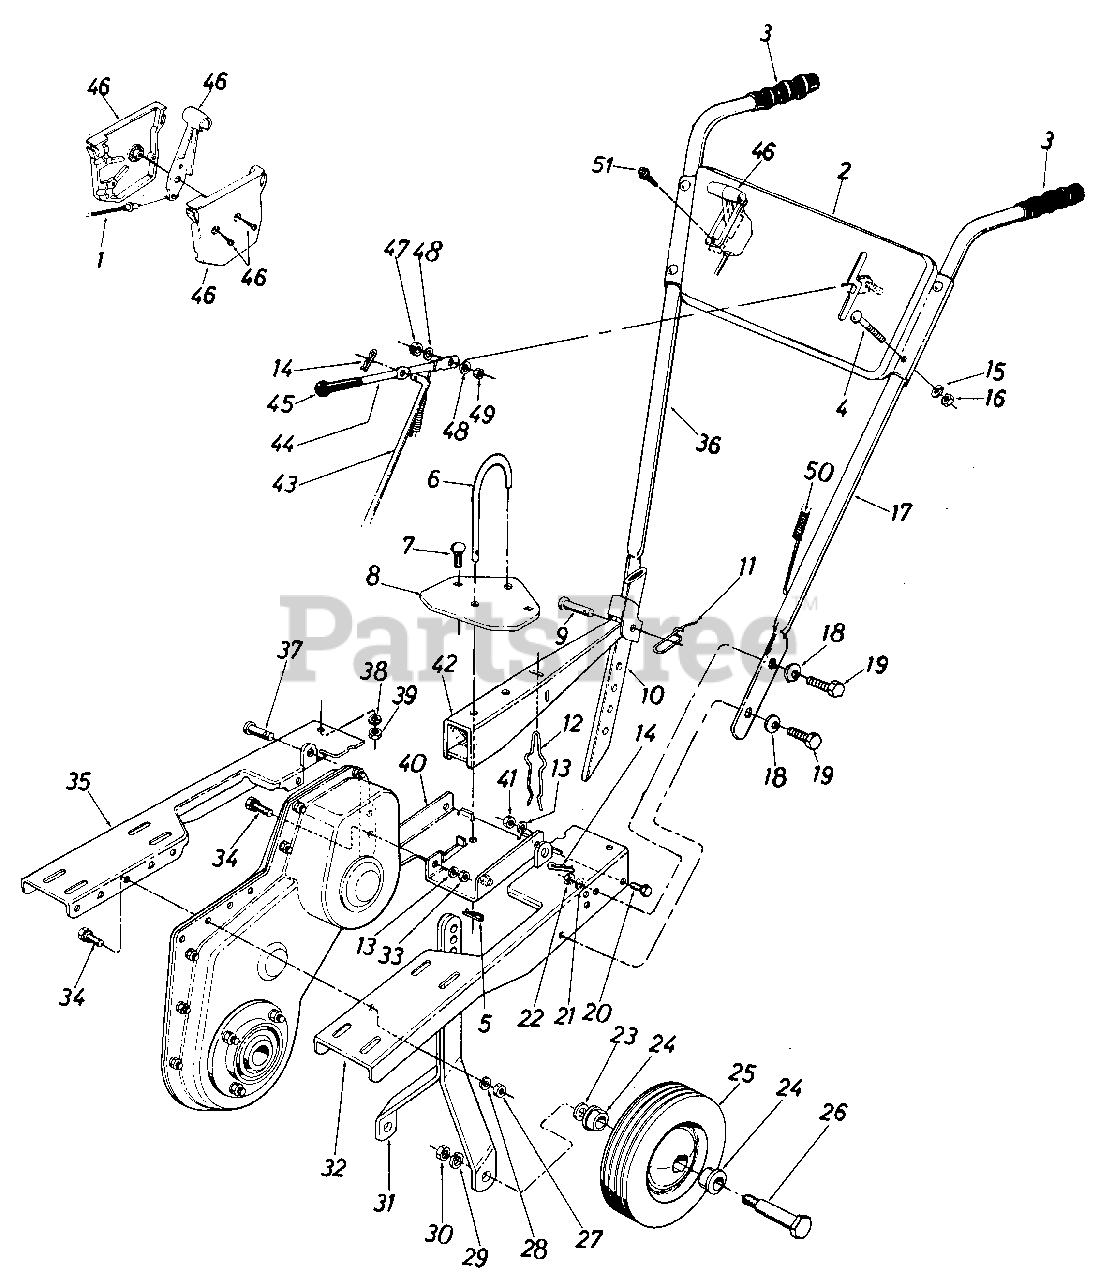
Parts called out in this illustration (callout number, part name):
1	WIRE-CONTROL
2	PANEL ASSY-CONTROL
3	GRIP-BLACK
4	BOLT-CARRIAGE 5/16-18 X 1.75
5	PIN-COTTER
6	PIN-CLEVIS .50 DIA
7	BOLT-CARRIAGE 5/16-18 X .75
8	PLATE-U CHANNEL
9	PIN-CLEVIS
10	BAR-DEPTH
11	PIN-SPRING
12	SPRING-DEPTH BAR
13	WASHER-LOCK-5/16
14	PIN-INTERN COT
15	WASHER-LOCK-5/16
16	NUT-HEX 5/16-18
17	HANDLE-LH
18	WASHER-BELL .400 ID X .88 X .060
19	SCREW-HEX 3/8-16 X 1.00
20	SCREW-HEX 5/16-18 X .75
21	WASHER-LOCK-3/8
22	NUT-HEX 3/8-16
23	WASHER-BELL .505 ID X 1.00 OD
24	BEARING-FLANGE
25	WHEEL ASSY-10 X 1.75
26	SCREW-SHLD
27	NUT-HEX 5/16-18
28	WASHER-LOCK-5/16
29	WASHER-LOCK-1/2
30	NUT-HEX INS L-1/2-20
31	BRACKET ASSY-WHL
32	CHANNEL ASSY-U-LH
33	NUT-HEX 5/16-18
34	SCREW-HEX SEMS 5/16-18 X 1.00
35	CHANNEL-ENG U
36	HANDLE-RH
37	PIN-CLEVIS
38	WASHER-LOCK-5/16
39	NUT-HEX 5/16-18
40	BRACKET ASSY-U CHANNEL
41	NUT-HEX 5/16-18
42	TAIL PIECE ASSY
43	ROD-CONTROL-CLUTCH
44	LEVER-CLUTCH
46	CONTROL-THROTTLE
47	WASHER-RUBBER
48	WASHER-FL-.344 ID X .88 OD X .063
49	NUT-HEX CENTER L-5/16-18
51	SCREW-TRUSS TAP
